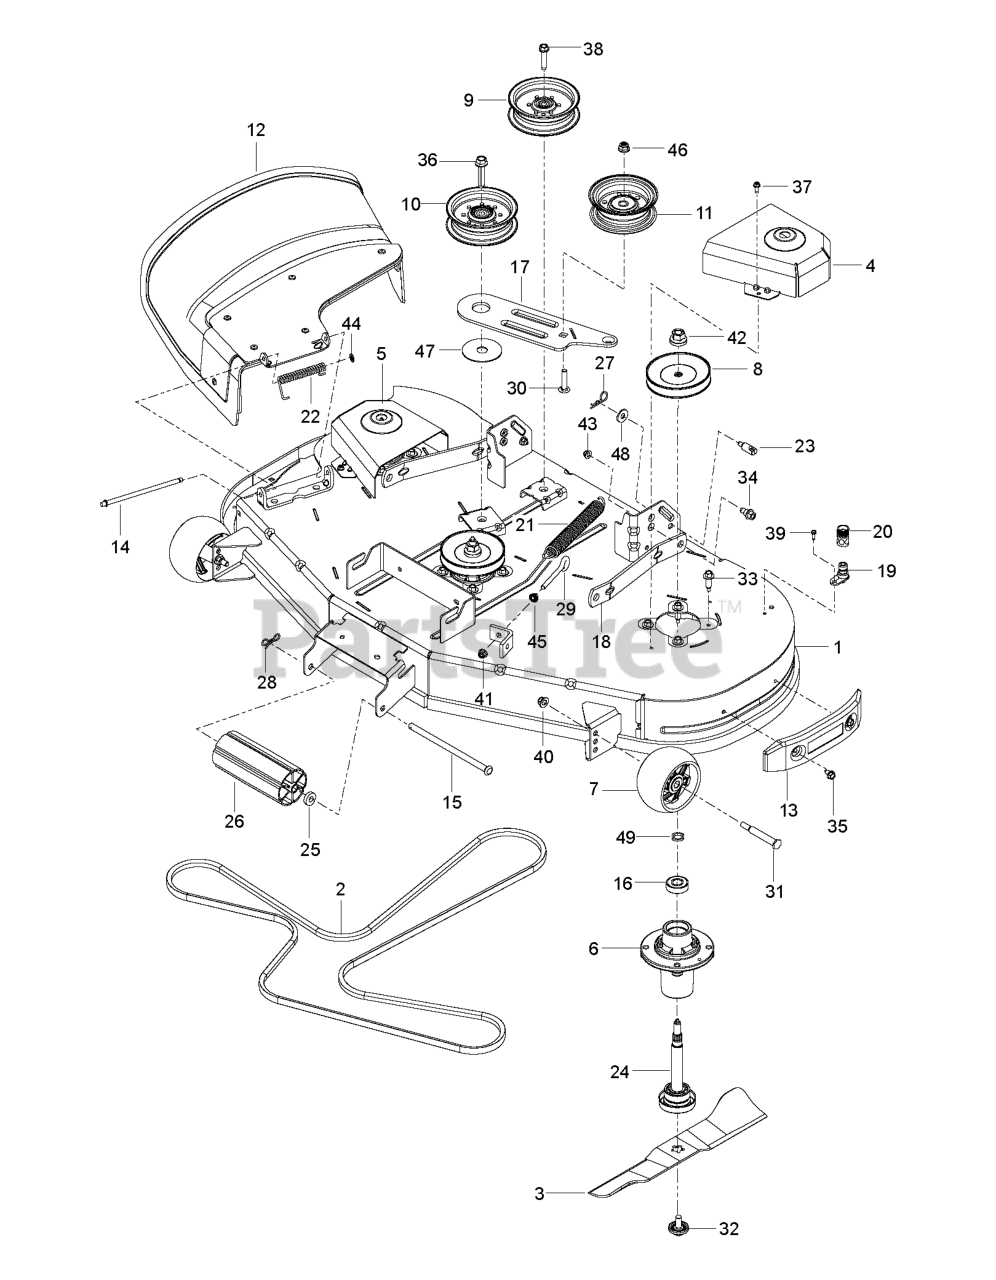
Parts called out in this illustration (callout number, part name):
1	DECK SVC.48.CC.RZ 668
2	BELT.DECK
3	BLADE.BAGGER.RES.CLRCT.48".BLK
4	COVER 48 CLEARCUT ZTR LH MANDR
5	COVER 48 CLEARCUT RH MANDREL B
6	MANDREL ASM, CAST IRON
7	WHEEL. GUAGE RALLY
8	MANDREL.PULLEY.38.BRIGHT.ZINC
9	PULLEY.IDLER.2006
10	PULLEY.IDLER.MWR.STATI.LH
11	PULLEY.IDLER.48"PRIMARY
12	DEFLECTOR.ASM.48".CLRCT.RES.OR
13	BUMPER.ASM.SIDE.TRIM.CLRCUT.48
14	ROD.HINGE
15	ROD.ROLLER.NOSE.NARROW.48"
17	ARM.PNT.CLUTCHING.EDIP
18	ARM.RFIXED.MOWER.SUSPNSIONX431
19	PORT.WASHOUT
20	COUPLING.QUICK CONNECT
21	SPRING.EXTENSION
22	SPRING.42.FCS.DEFLECTOR
23	STUD.FASTNER.W/ANTI-ROTATE
24	SHAFT ASM MANDREL
25	BUSHING.NOSE.ROLLER
26	NOSE ROLLER 48"
27	HAIRPIN #4
28	PIN.COTTER.5/16.BOW TI
29	EYE BOLT 5/16 X 3.50
30	BOLT
31	BOLT.SHOULDER.3/8-16X3-5/8.
32	BOLT.WASHER.ASM.7/16-2
33	BOLT.HEX.WASHR.HED.313-18X1.19
34	BOLT.SHOULDER
35	BOLT.5/16HEX.WHS.HD
36	SCREW.7/16-14 X 2.125.WASHER
37	SCREW.1/4-20X5/8
38	SCREW LT
39	SCREW
40	NUT 3/8-16 HEX FLG NYLOC ZD
41	5/16-18 NYLOC FLANGE NUT
42	NUT.FLANGE.LOCK.TOP
43	NUT LOCK HEX FLANGE 5/16-18
44	NUT PUSH M
45	NUT 5/16C WHIZ
46	LOCKNUT
48	WASHER
49	WASHER.SPACER.MANDREL
